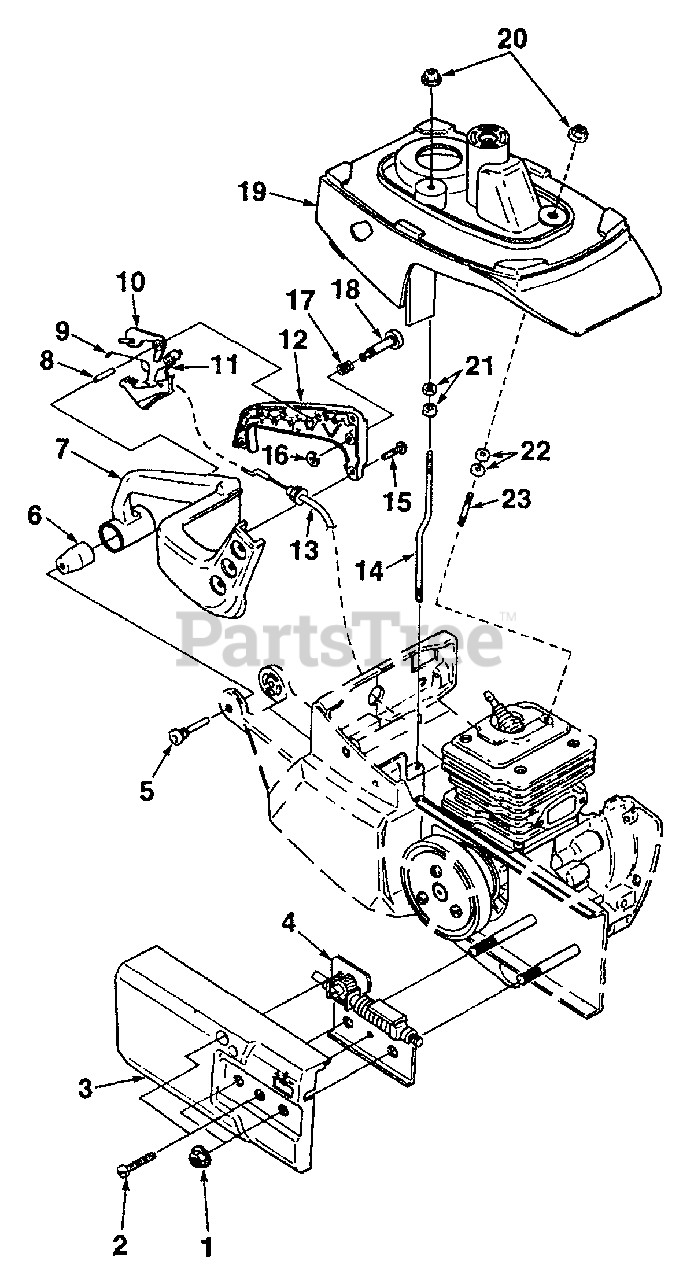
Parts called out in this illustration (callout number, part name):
1	NUT-Hex Flange (5/16-18)
2	SCREW-Taptite (8-32 X 5/8")
3	COVER-Clutch
4	GEAR KIT
5	PIN-Isolator
6	ISOLATOR-Vibration
7	HANDLE-Rear
8	PIN-Trigger
9	SPRING-Throttle
10	LOCK-Trigger
11	TRIGGER & SWIVEL
12	COVER-Handle
13	CABLE-Throttle
14	STUD-Offset (10-24)
15	SCREW-Plastite (8-16 X 5/8")
16	RING-Retaining
17	SPRING-Compression
18	PIN Throttle Lock
19	COVER-Cylinder
20	NUT-Hex Conical
21	NUT-Hex
22	SPACER-Insulating
23	STUD (10-24 X 1.06")
